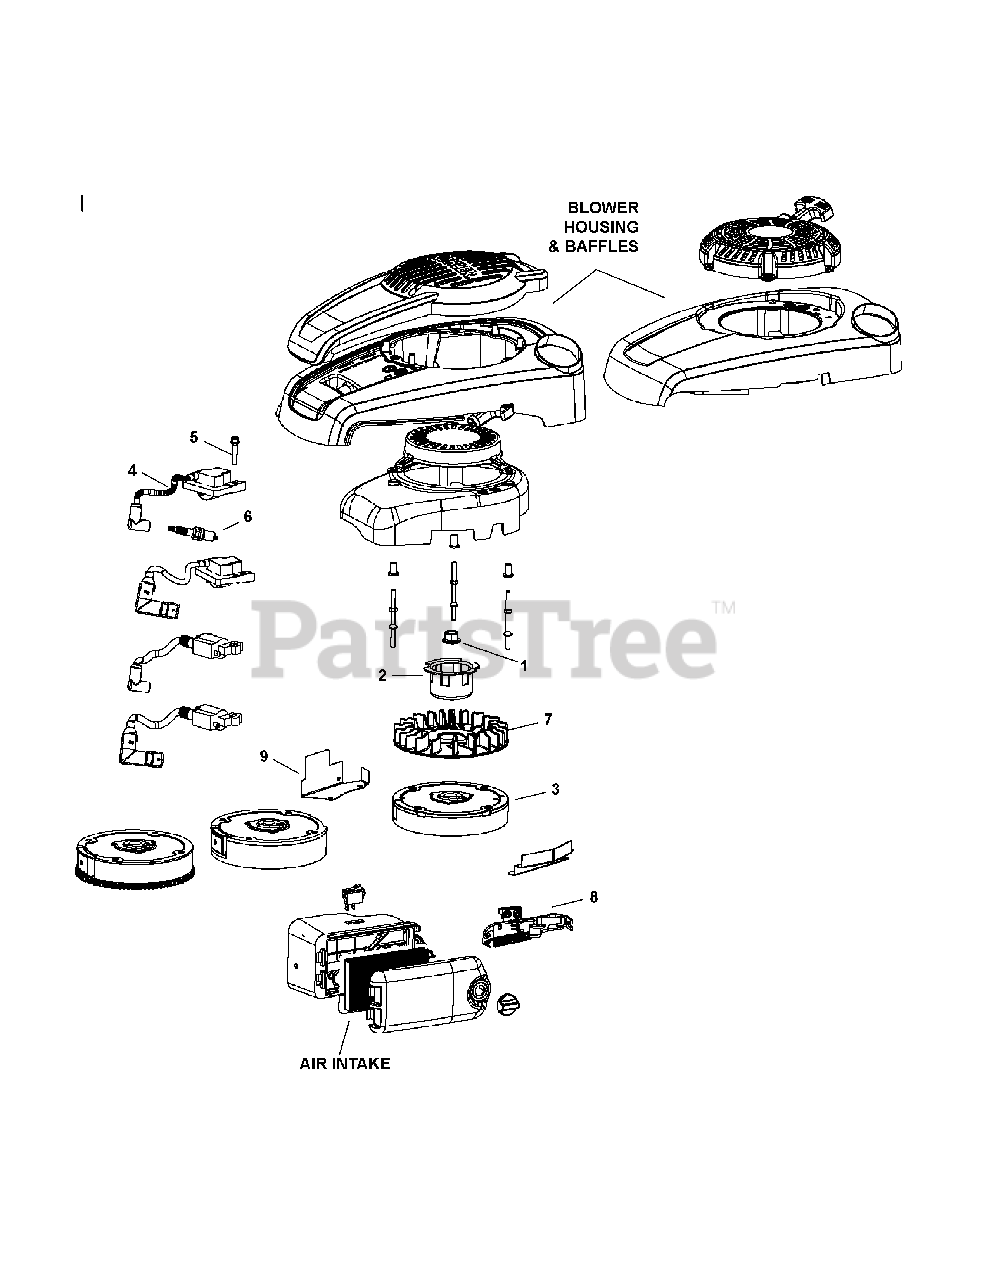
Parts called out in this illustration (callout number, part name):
1	Nut, Flywheel (w/ serrations)
3	Flywheel Assembly
4	Ignition Module
5	Hex Flange Screw, M6
6	Spark Plug
7	Flywheel Fan
8	Brake Assembly, Carb Side
